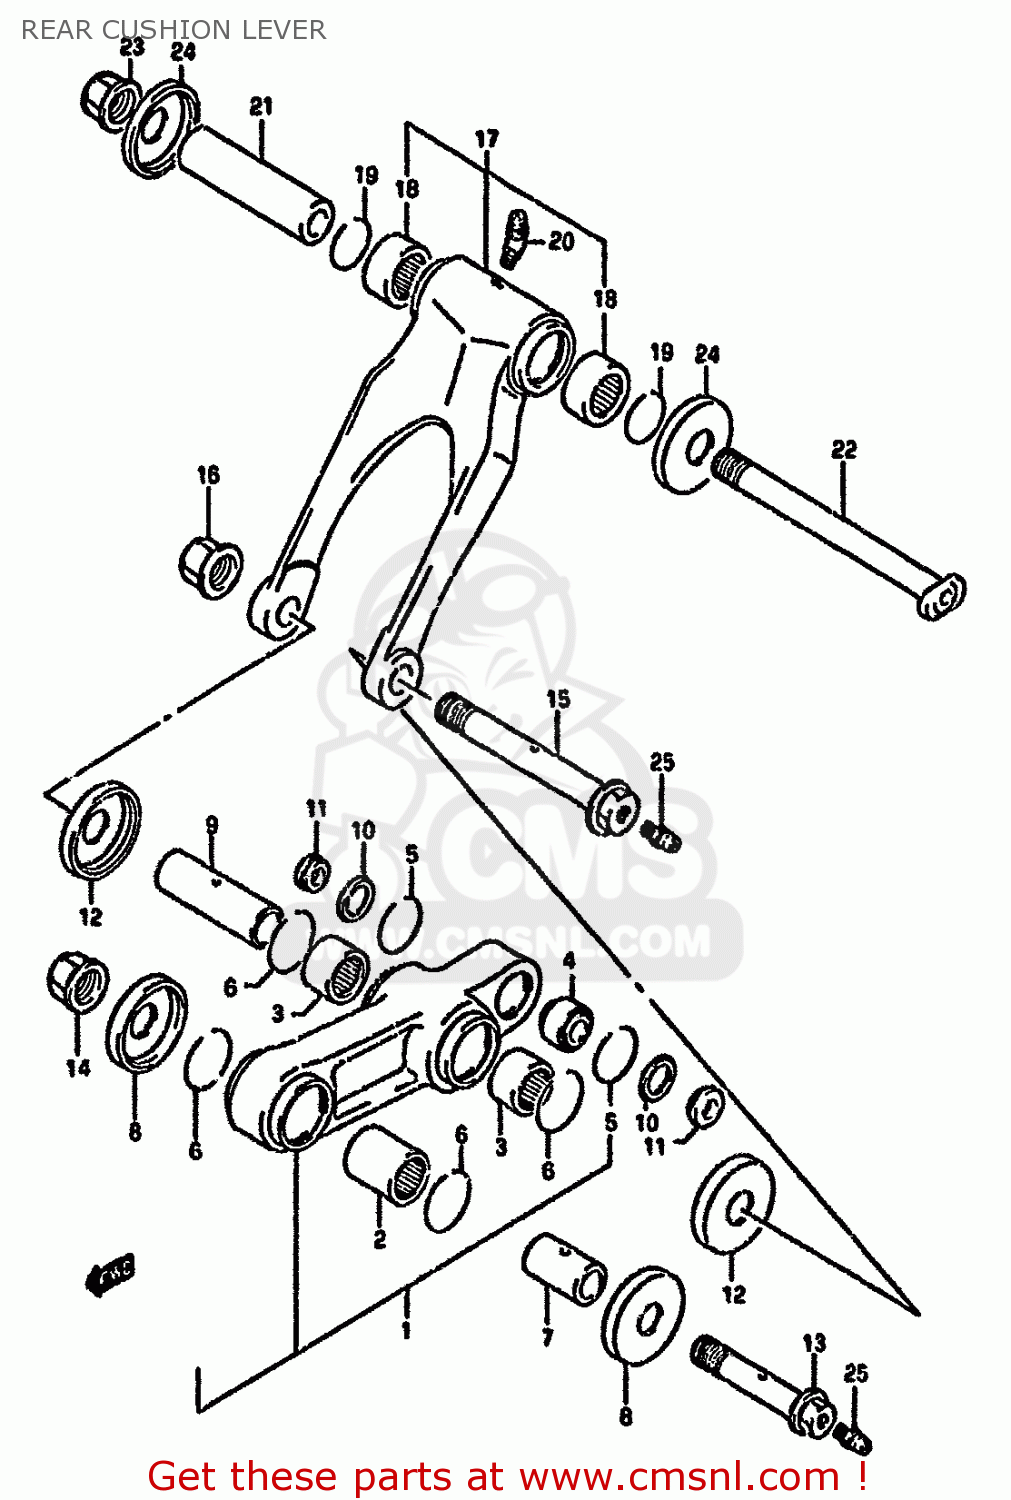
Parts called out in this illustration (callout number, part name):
1	LEVER SET,REAR CUSHION
2	BEARING(20X27X25)
3	BEARING(21X27X20)
4	BEARING,RR CUSHION LEVER RR
5	RING,BEARING STOPPER
6	CIRCLIP
7	SPACER,RR CUSHION LEVER FR
8	SEAL,REAR CUSHION LEVER
9	SPACER,RR CUSHION LEVER CTR
10	SEAL,RR CUSHION LEVER RR DUST
11	SPACER,RR CUSHION LEVER RR
12	SEAL,REAR CUSHION LEVER
13	BOLT,REAR CUSHION LEVER
14	NUT 12MM
15	BOLT,RR CUSHION LEVER CTR
16	NUT
17	ROD SET,RR CUSHION LEVER
18	BEARING(21X27X20)
19	CIRCLIP
20	NIPPLE,GREASE
21	SPACER,RR CUSHION ROD
22	BOLT,RR CUSHION ROD
23	NUT
24	SEAL,REAR CUSHION LEVER
25	GREASE NIPPLE
